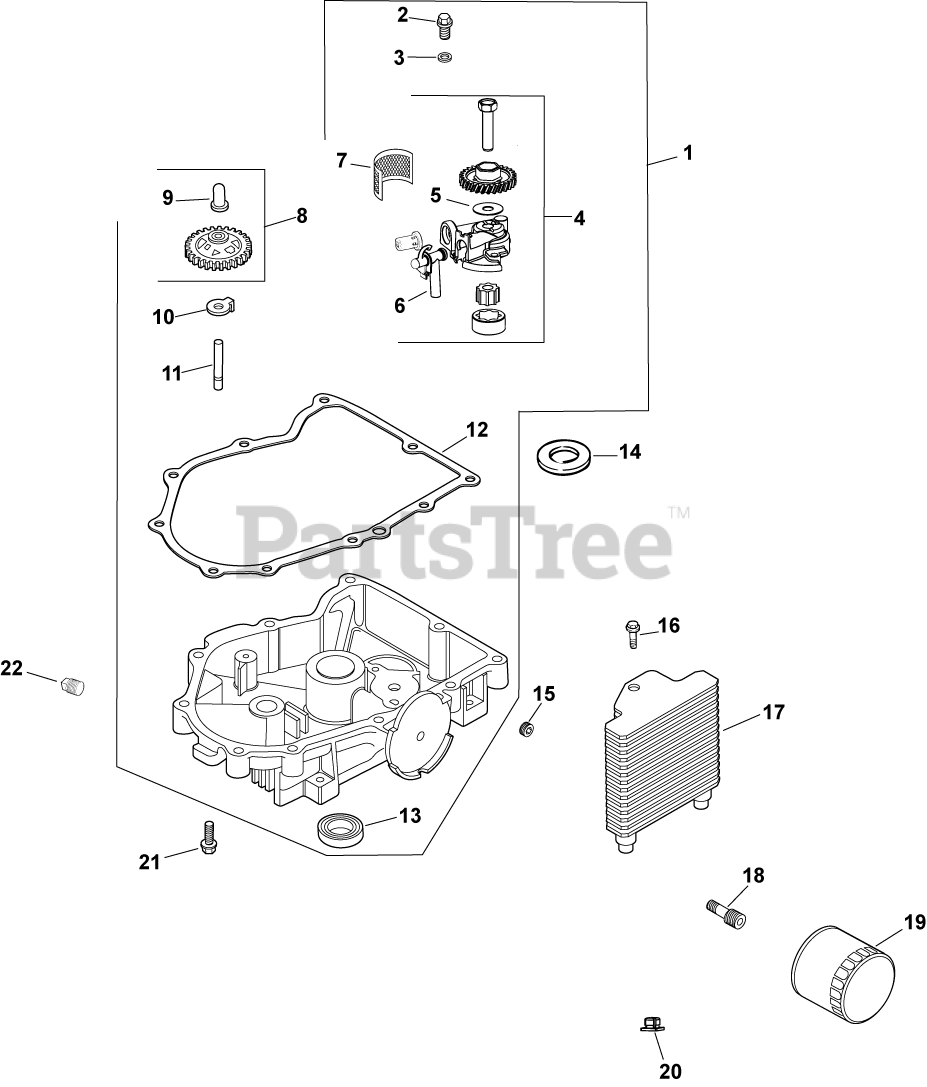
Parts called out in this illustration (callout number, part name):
1	KIT, OIL PAN ASSEMBLY - (#2419932S)
2	SCREW,FLG THD FRM M6X1.0X25-(#25086395S)
3	WASHER, FLAT 6 MM
4	PUMP ASSEMBLY, OIL-USE 24 393 53-S
5	O-RING, OIL PICK-UP
6	KIT, OIL PICK-UP TUBE
7	SCREEN, OIL
8	KIT, GOVERNOR GEAR W/PIN
9	PIN, GOVERNOR REGULATING
10	TAB, LOCKING
11	SHAFT, GOVERNOR GEAR
12	KIT,OIL PAN GASKET USE 24 041 66-S
13	SEAL, OIL
14	SHIM, THRUST (BLACK .686MM)
15	PLUG, PIPE CTSK 3/8"
16	SCREW, TAP M6X1.7X18
17	COOLER, OIL
18	NIPPLE, OIL FILTER
19	OIL FILTER
20	NUT, PLASTIC (KM)-USE 25 100 37-S
21	SCREW, FLG M8X1.25X45
22	PLUG, HD PIPE 3/8"
